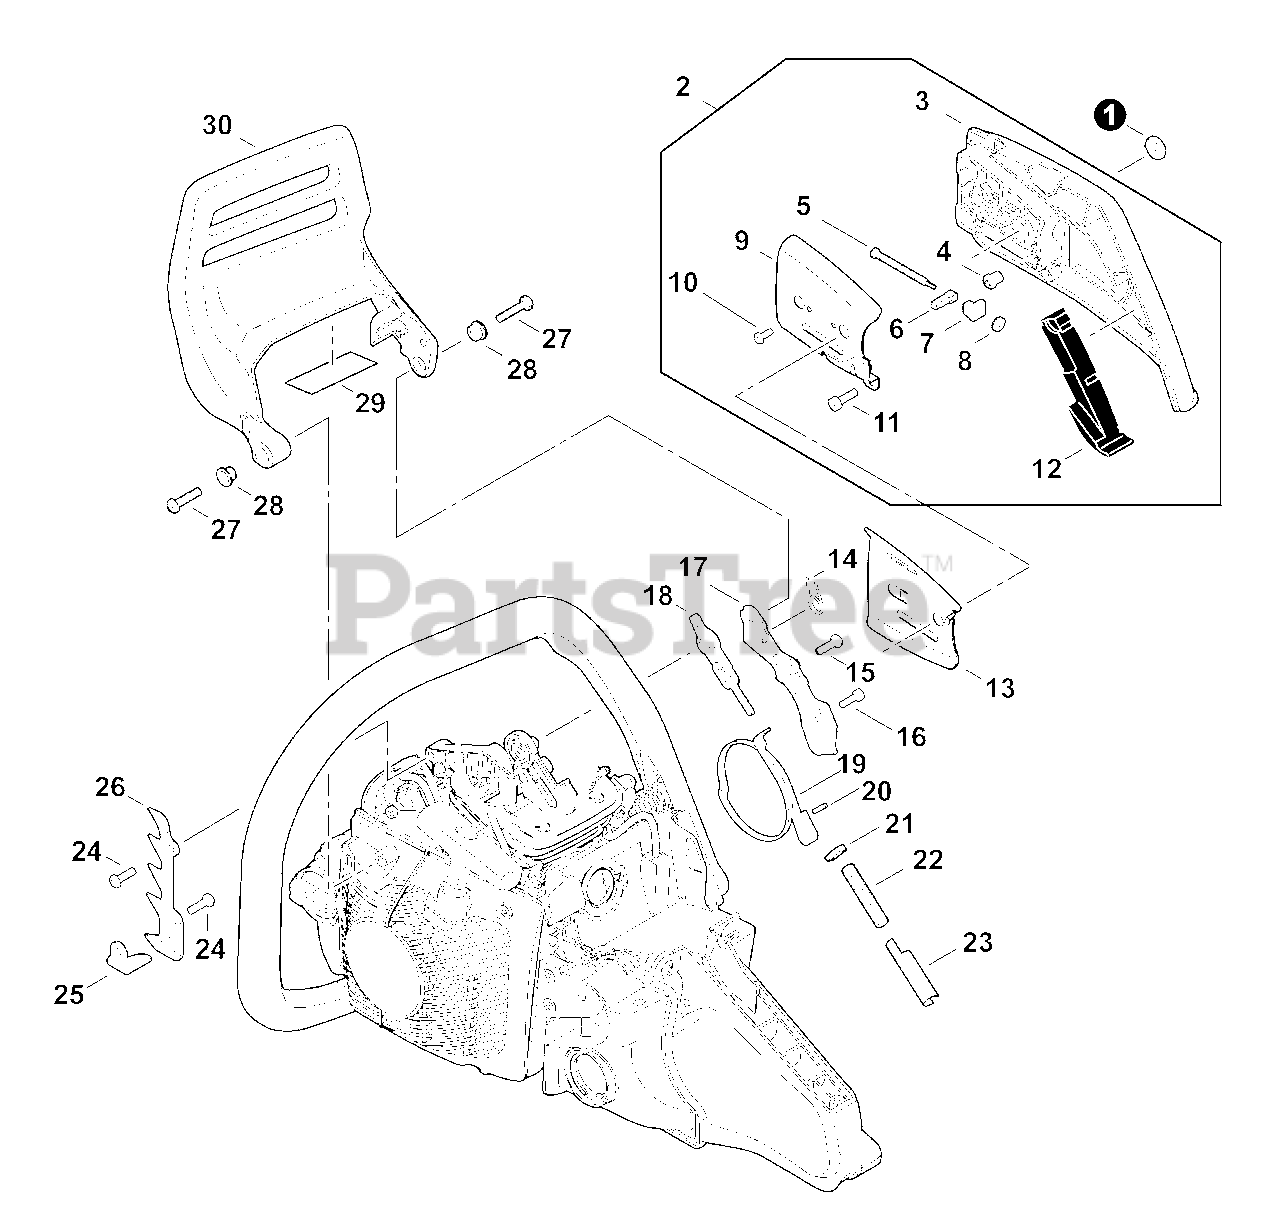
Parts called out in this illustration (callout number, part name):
2	GUARD KIT, SPROCKET
3	GUARD, SPROCKET
4	GEAR, BEVEL
5	SCREW, CHAIN TENSION 63 MM
6	TENSIONER, CHAIN
7	COLLAR 8
8	GEAR, BEVEL
9	PLATE, GUIDE - OUTER
10	SCREW 3×6
11	BOLT, TORX 4×12
12	CUSHION
13	PLATE, GUIDE - INNER
14	SPRING, TORSION
15	BOLT, TORX 5×16
16	BOLT, TORX 4×12
17	COVER, BRAKE
18	CONNECTOR, BRAKE
19	BAND, BRAKE
20	PIN, SPRING 3x-9.8
22	SPRING, COMPRESSION Ø12×70.5
23	PLATE, SIDE
24	BOLT, TORX 5×16
25	CHAIN CATCHER
26	SPIKE, BUMPER
27	BOLT, TORX 5×16
28	COLLAR 11.2×16.2×T0.6
29	SHIELD, HEAT 75×27×0.15
30	LEVER, BRAKE
